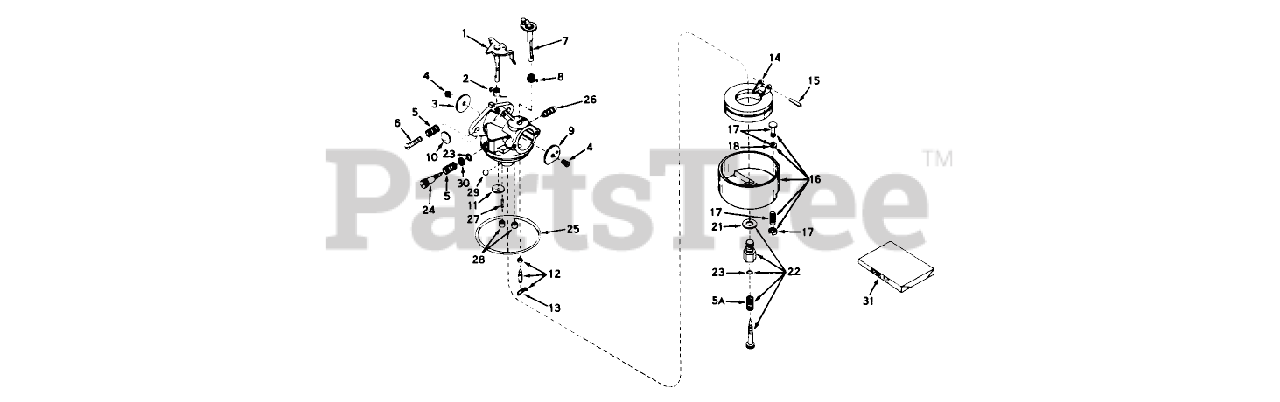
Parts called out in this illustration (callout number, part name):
1	Shaft/Lever-Throttle
2	Spring, Return
3	Shutter-Throttle
4	Screw-Shutter
5	Spring-Tension
5A	Spring
6	Screw-Throttle Crack Screw / Idle Speed
7	Shaft Lever Assy., Choke
8	Spring, Choke return
10	Plug-Welch, Idle Mixture Well
11	Plug-Welch, Atmospheric Vent
12	Inlet Needle, Seat Clip Assy. (Incl. No. 13)
13	Clip-Spring
14	Float,Carburetor
15	Shaft-Float
16	Bowl Drain Assy., Float (Incl. No. 17)
17	Plunger Assy., Drain (Incl. Ref. 18)
18	Gasket-Plunger, Drain
21	Washer-Bowl Nut
22	Adjustment Screw Assy., Main (Incl. Nos. 5A, 21 23)
23	ORing
24	Screw, Idle Adj.
25	O Ring-Bowl, Float
26	Fitting, Fuel inlet
28	Plug, Cup
29	BalI, Steel
30	Washer
31	Repair Kit (Incl. items marked *)
